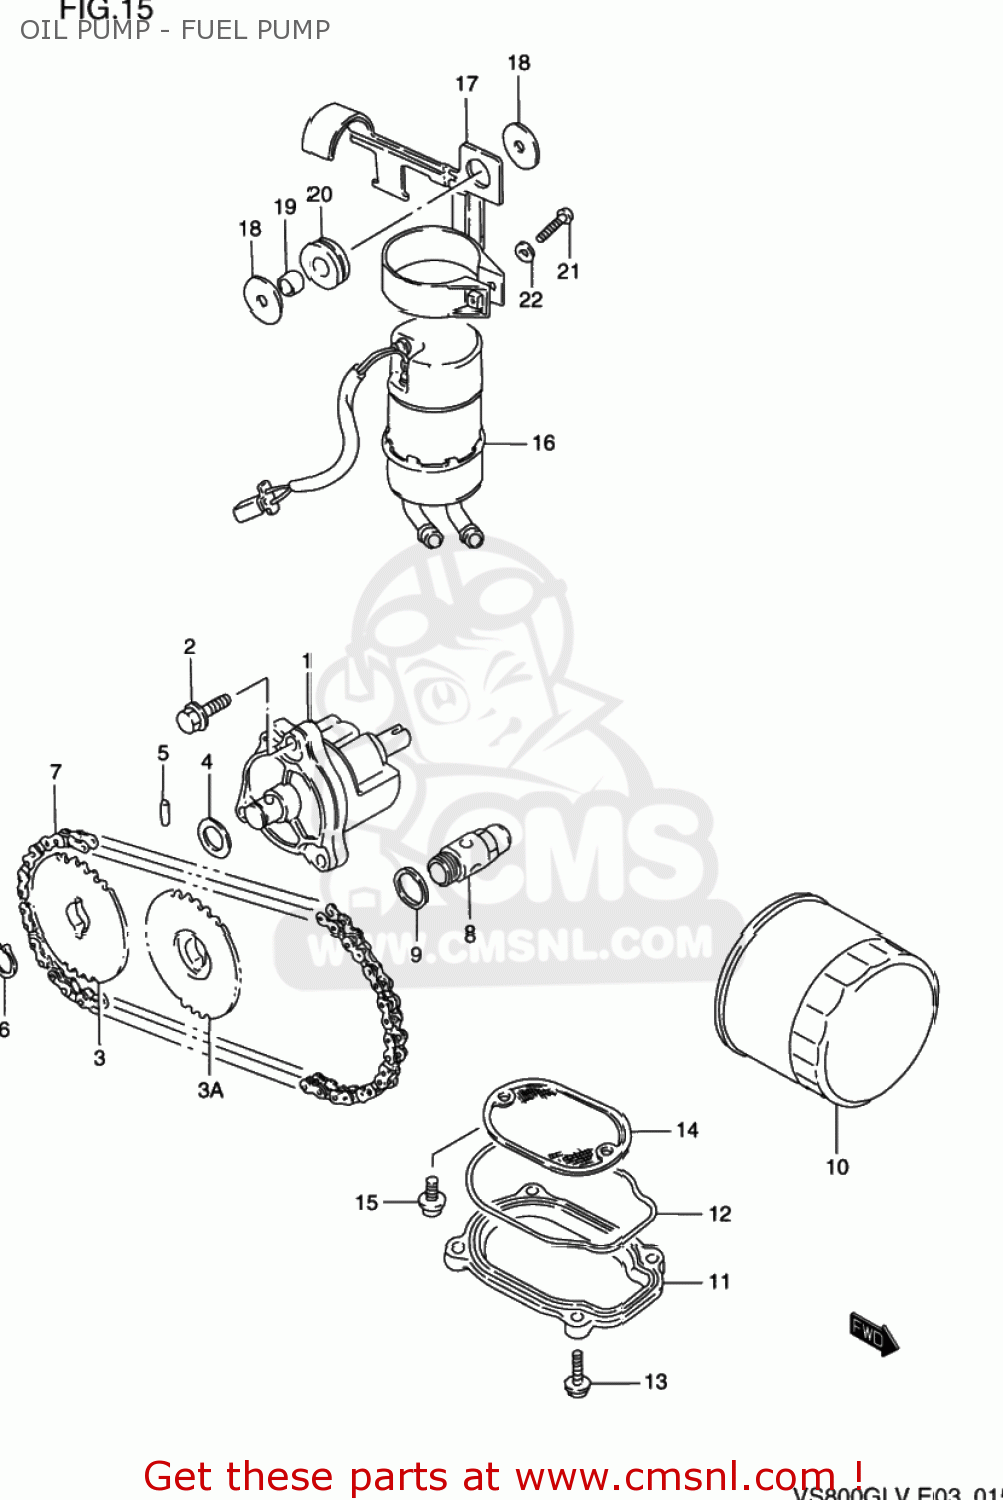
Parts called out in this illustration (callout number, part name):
1	PUMP ASSY,ENGINE OIL
2	BOLT
3	SPROCKET,OIL PUMP DRIVEN
3A	SPROCKET,OIL PUMP DRIVEN
4	SHIM
5	PIN(5X18)
6	CIRCLIP,12 MM
7	CHAIN,OIL PUMP DRIVE
8	VALVE ASSY,OIL RELIEF
9	GASKET(16X22X2) (NAS)
10	FILTER ASSEMBLY,ENGINE OIL
11	CAP,OIL STRAINER
12	O RING,OIL STRAINER CAP
13	BOLT
14	STRAINER,ENGINE OIL
15	SCREW
16	PUMP ASSY,FUEL
17	BRACKET,FUEL PUMP
18	WASHER (6.5X24X1.6)
19	SPACER(6.5X10.5X6.5)
20	CUSHION
21	SCREW
22	WASHER 4MM
